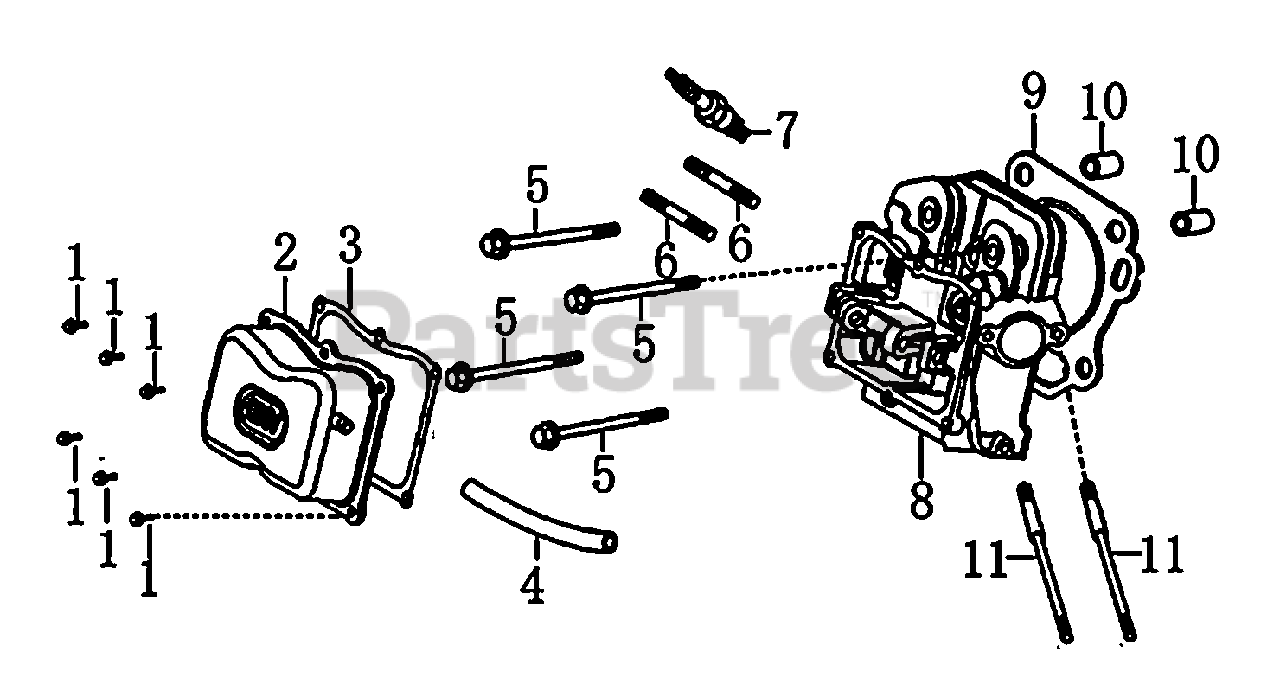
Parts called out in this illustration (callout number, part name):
1	BOLT, FLANGE
2	COVER, VALVE
3	GASKET,VALVE COVER
4	TUBE, BREATHER
5	BOLT, FLANGE, 10X80
6	BOLT, STUD, EXHAUST
7	SPARK PLUG
8	HEAD, CYLINDER
9	GASKET, CYLINDER HEAD
10	PIN, DOWEL
11	BOLT, STUD, INTAKE
